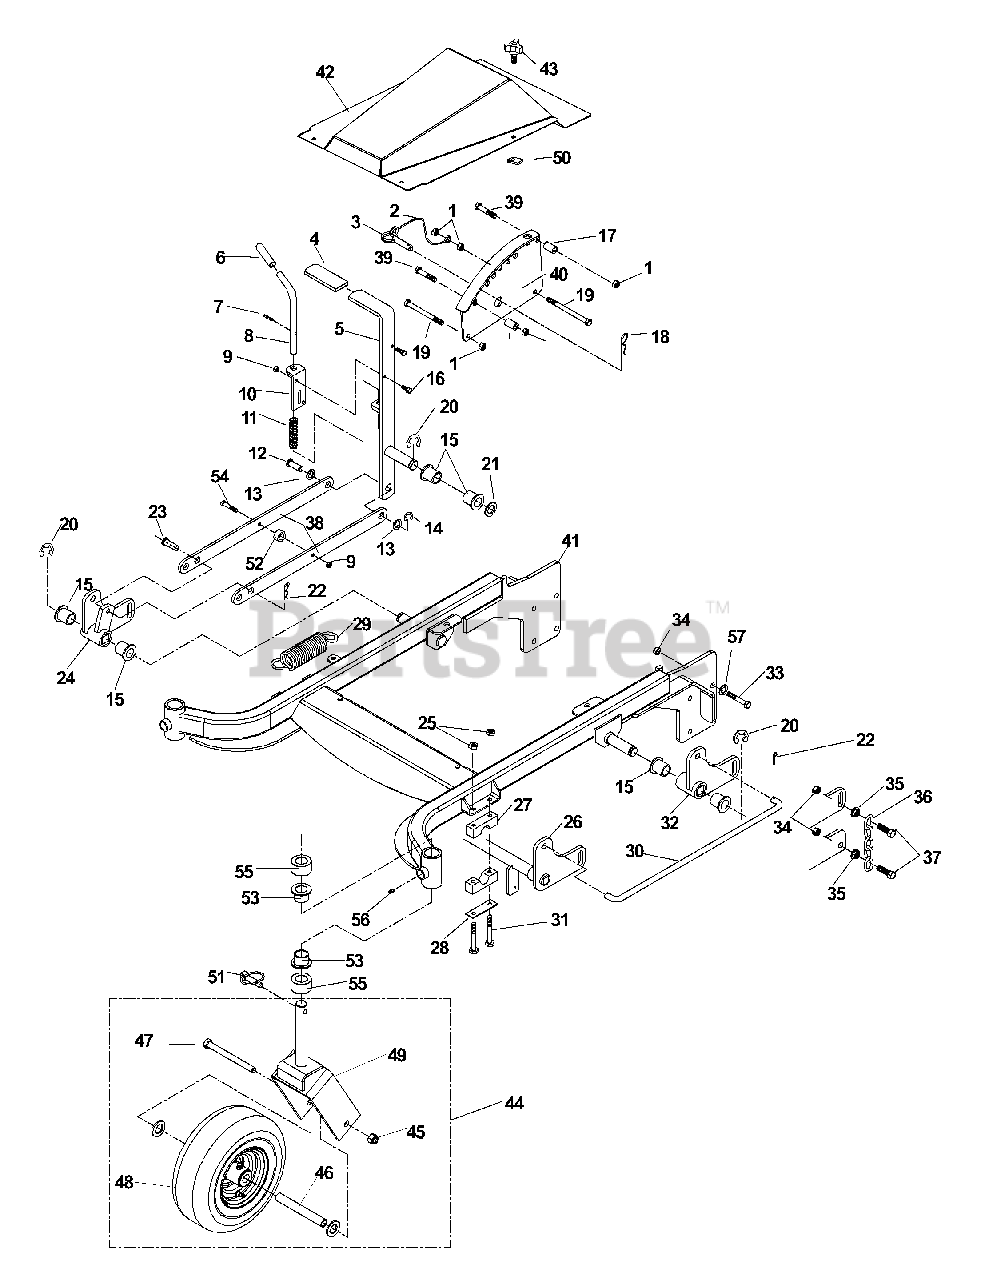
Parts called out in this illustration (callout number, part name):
1	NUT, 3/8, CENTER LOCK
5	LIFT LEVER
9	NUT, 1/4, CENTER LOCK
12	CLEVIS PIN
13	BUSHING, 5/8, MACHINE
14	E-RING, 5/8
15	BUSHING, 7/8, FLANGED
16	HCS 1/4C X 3/4
18	HAIRPIN, 2 1/2
19	HCS, 3/8C X 4 1/2
20	E-RING, 7/8
21	BUSHING, MACHINE
22	COTTER PIN, 5/32 x 1 1/4
23	CLEVIS PIN, 3/8 X 1 1/8
24	BELLCRANK, RIGHT
25	NUT, 5/16, CENTER LOCK
26	LIFTARM, FRONT
27	PILLOW BLOCK
28	REINF. PLATE
30	LINK, DECK LIFT
31	HCS, 5/16C X 2 1/2
32	BELLCRANK, LEFT
33	HCS, 7/16C X 1
34	NUT, 7/16C, CENTER LOCK
35	NUT, 7/16C, WHIZ
36	LIFT CHAIN
37	HCS, 7/16C X 1 1/2
38	FLAT LINKAGE
39	HCS, 3/8C X 2
40	HEIGHT ADJ. PLATE
43	KNOB
44	CASTER ASSEMBLY, COMPLETE
45	NUT, 1/2C, NYLOC
47	HCS, 1/2C X 5 1/2
48	TIRE, COMPLETE
48	TIRE
48	VALVE STEM
48	BEARING, FLANGE
48	BEARING, ROLLER, 3 1/4
48	ZERK
49	FORK, CASTER
51	LYNCH PIN, 7/16
53	BUSHING, CASTER
54	HCS, 1/4C X 1 1/4
56	ZERK
57	WASHER, 7/16
